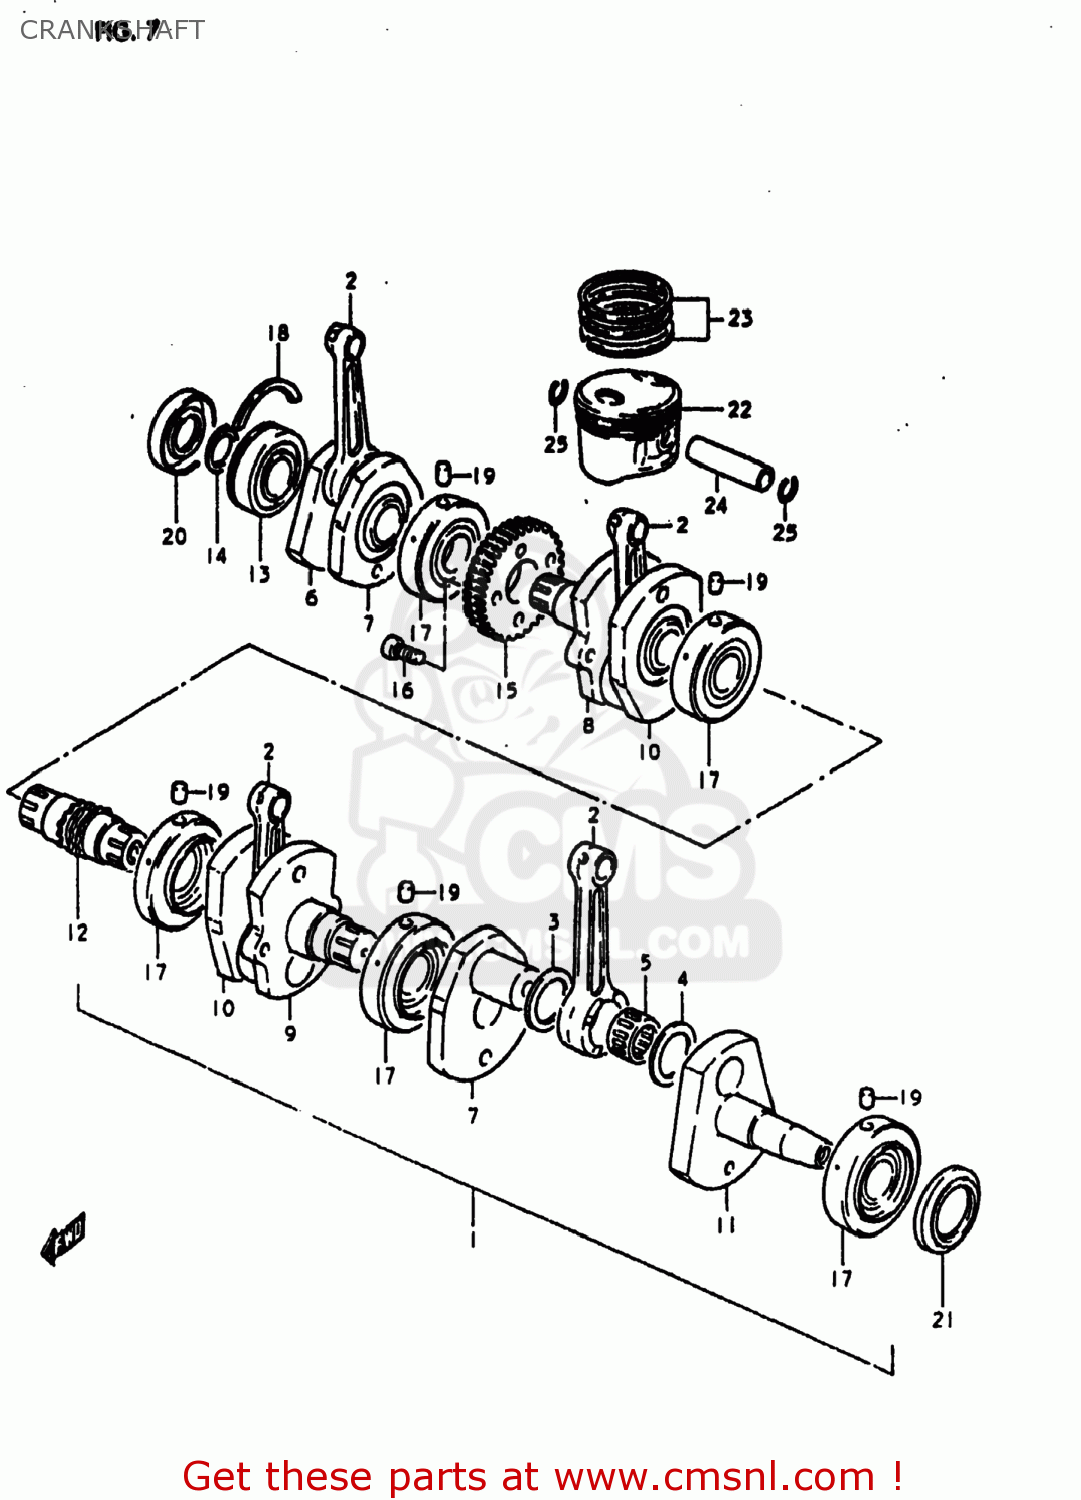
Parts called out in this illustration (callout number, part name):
1	CRANKSHAFT ASSEMBLY
2	ROD,CONNECTING
3	WASHER (29X48X2)
4	WASHER (29X48X1)
5	BEARING(29X39X20)
6	CRANKSHAFT
7	WEB,CRANK
8	CRANKSHAFT
9	CRANKSHAFT
10	WEB,CRANK,MIDDLE
11	CRANKSHAFT,LEFT
12	SHAFT,TIMING CHAIN DRIVE
13	BEARING(30X72X19)
14	CIRCLIP,30MM
15	GEAR,PRIMARY DRIVE
16	BOLT
17	BEARING
18	C RING
19	PIN
20	SEAL,OIL(30X72X11)
21	SEAL,OIL(47.3X60X6.5)
22	PISTON
23	RING SET,PISTON
24	PIN,PISTON (18MM)
25	CIRCLIP
